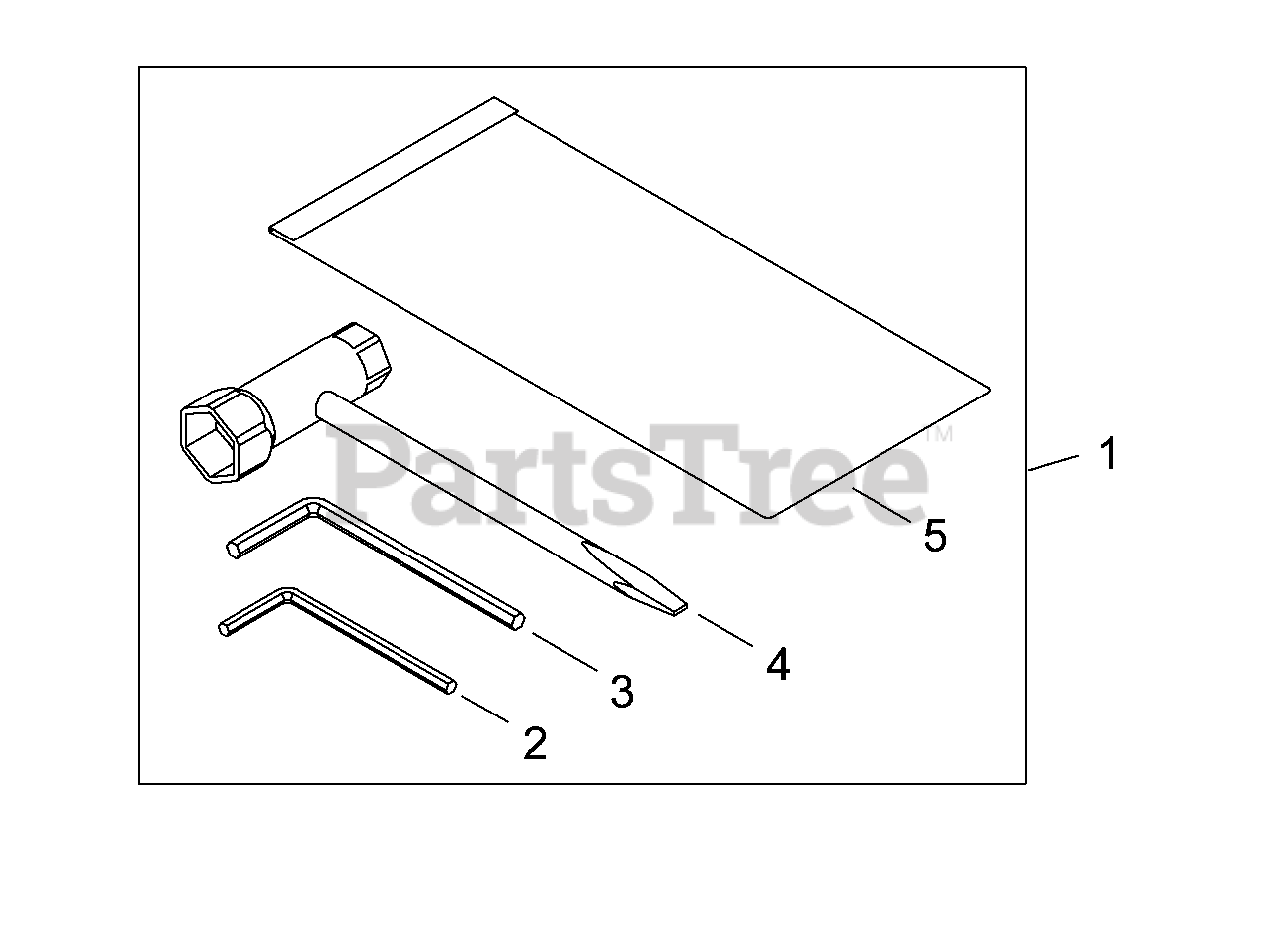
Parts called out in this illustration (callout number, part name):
1	TOOL KIT
2	HEX KEY - 4mm
3	HEX KEY - 6mm
4	T-WRENCH - 13X19mm
5	BAG, TOOL
